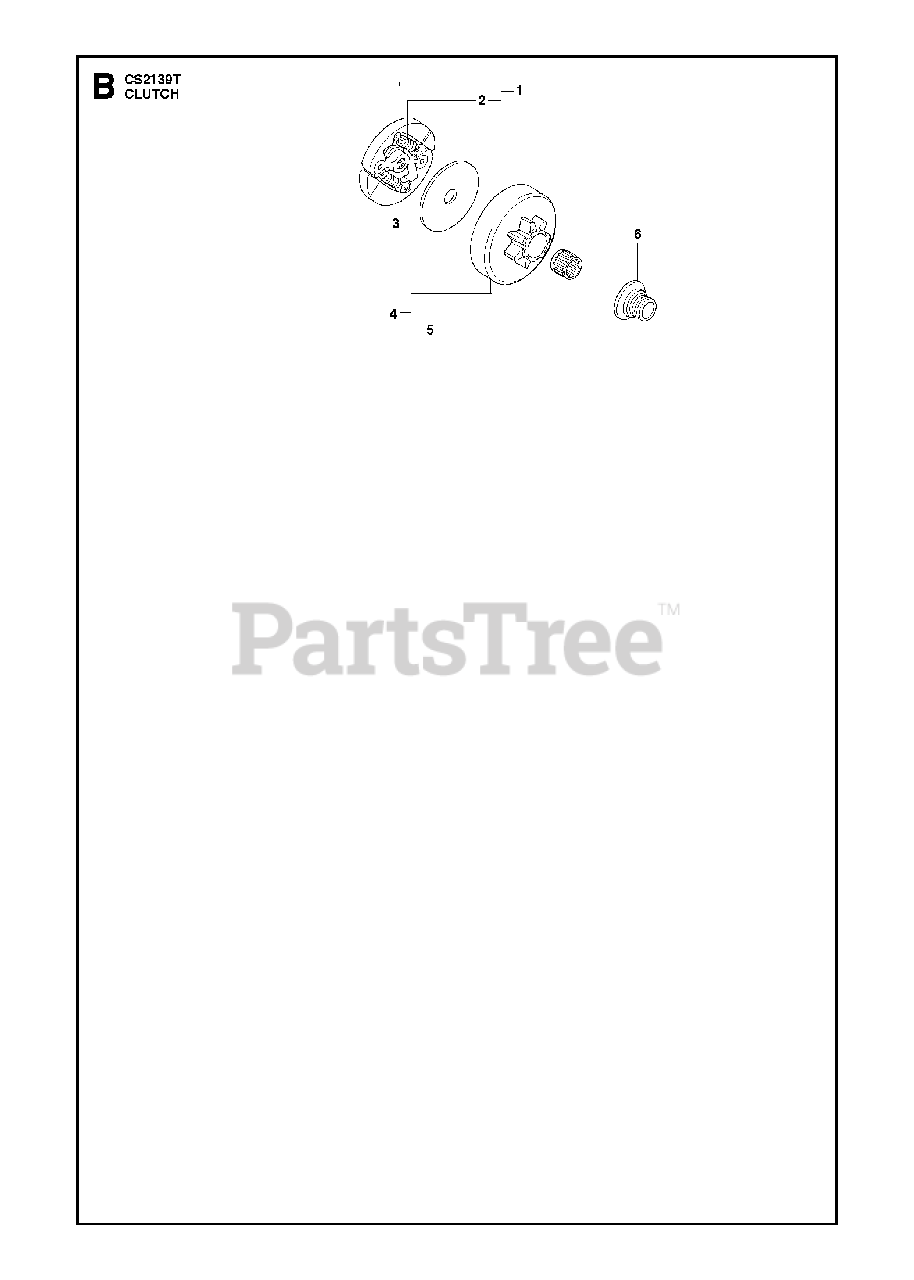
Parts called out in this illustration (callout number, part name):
2	SPRING
4	CLUTCH DRUM
5	SUPPORT BUSHING.
6	PINION
